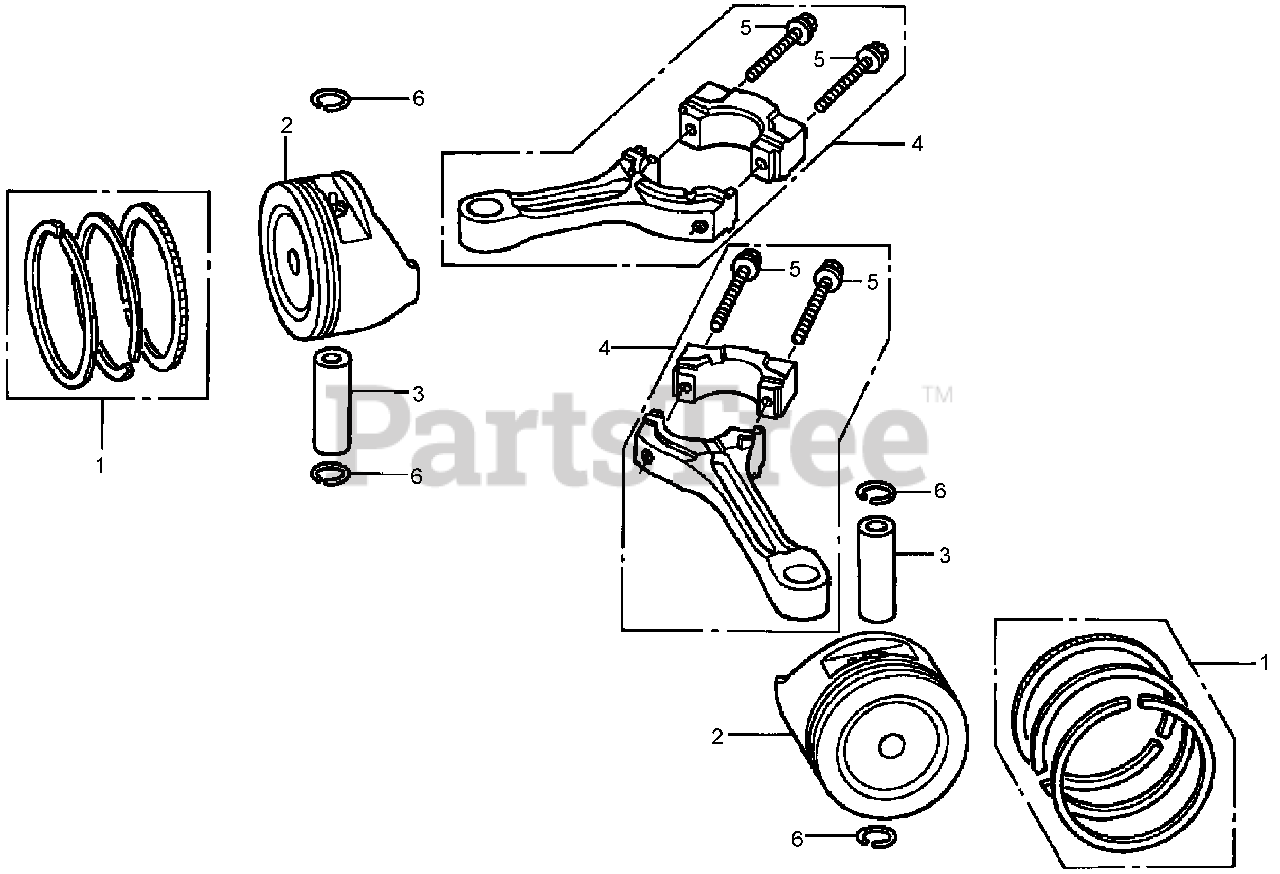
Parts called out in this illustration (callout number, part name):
1	PISTON RING SET (STD) (NIPPON)
1	PISTON RING SET
2	PISTON (STD)
3	PIN-PISTON
4	CONNECTING ROD ASM
5	BOLT-ROD, CONNECTING (6X37)
6	CLIP-PIN, PISTON (18 mm)
